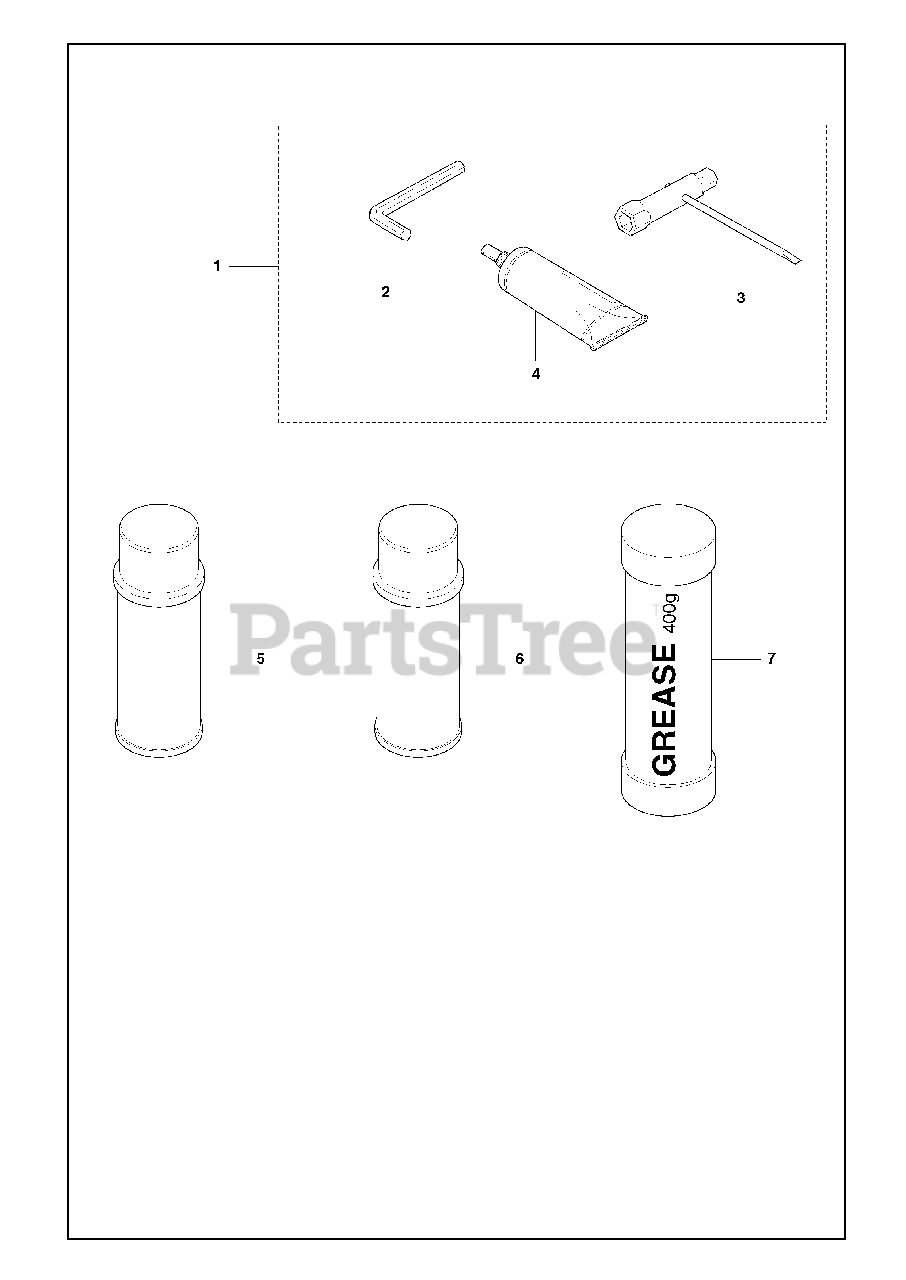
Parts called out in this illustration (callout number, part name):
1	CARBURETOR
2	CHOKE SHAFT
4	DISC
16	PIN FULCRUM
18	SPRING
19	INLET NEEDLE
24	SPRING
26	LOW SPEED NEEDLE
27	NEEDLE HIGH SPEED
30	THROTTLE FLAP
33	SPRING THROTTLE
35	PUMP DIAPHRAGM
41	GASKET KIT (ZAMA GND39)
42	CARBURETOR KIT (ZAMA RB69)
